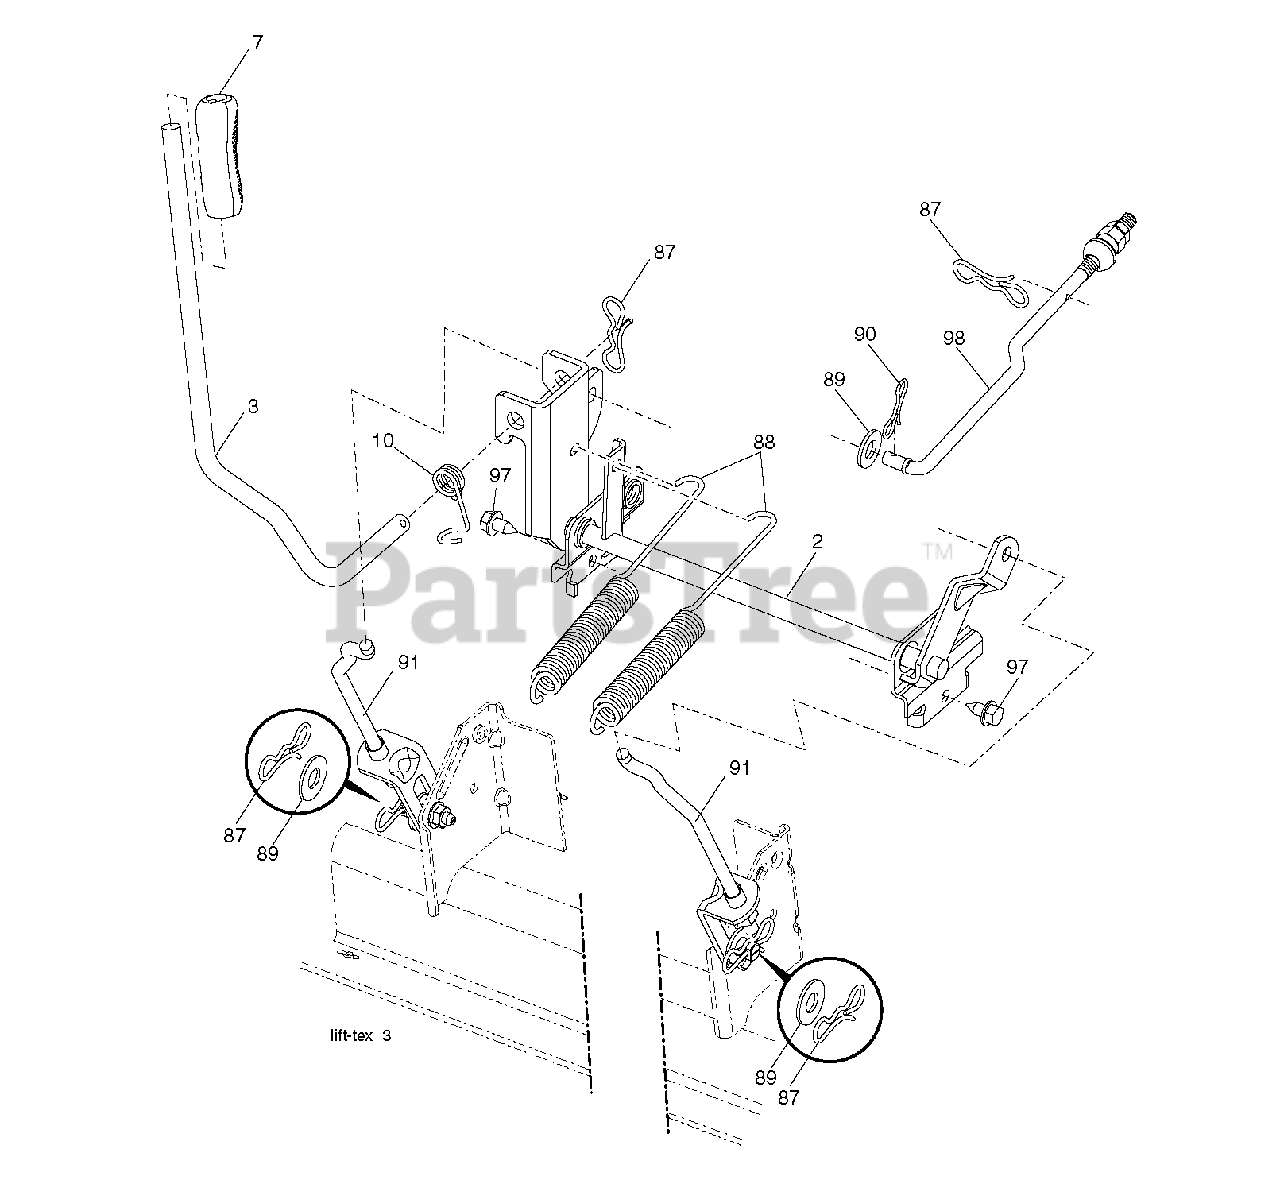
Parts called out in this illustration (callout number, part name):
2	SHAFT.ASM.CROSS.LIFT
3	LEVER.LIFT.HANDLE.GT
7	GRIP.HANDLE.LIFT.PVC.BLACK
10	SPRING.TORSION.LIFT.HANDLE
87	PIN.COTTER.7/16.BOW TI
88	SPRING.LIFT.ASSIST
89	WASHER.CLEAR.ZINC
90	PIN.COTTER.5/16.BOW TI
91	LINK.LIFT.ASM.REAR.GT.
97	SCREW, 3/8-16X3/4
98	LINK.ASM.SUSP.FRONT.MWR.10.5
